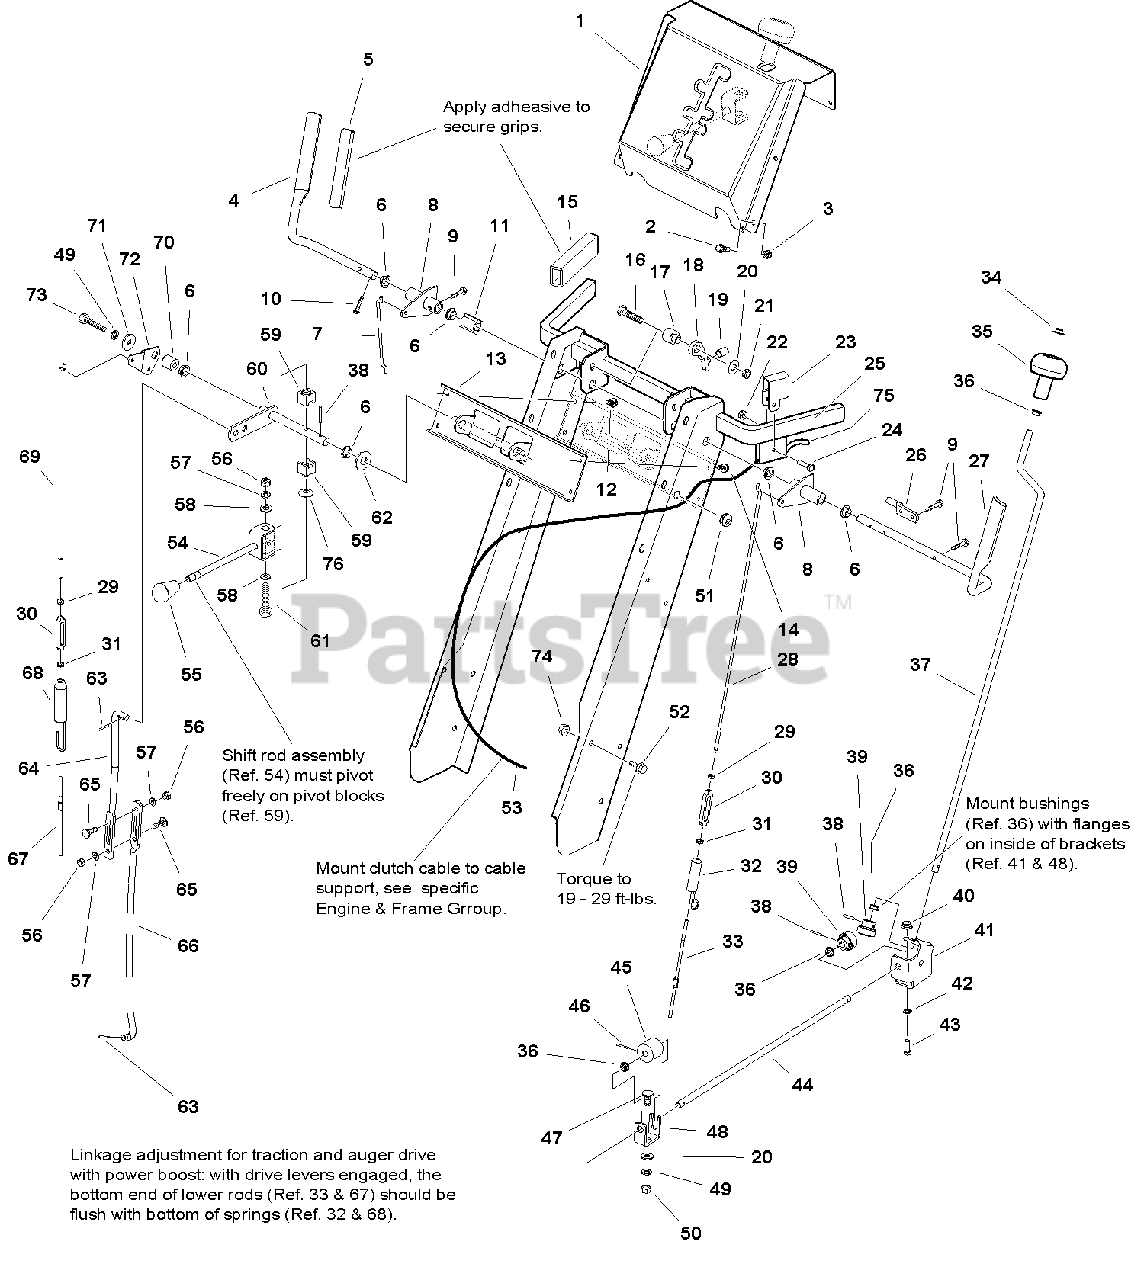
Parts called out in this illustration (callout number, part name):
2	CAPSCREW, Hex Head, 1/4-20 x 3/4
3	NUT, Hex Lock, 1/4-20
4	HANDLE, Clutch, RH
6	BUSHING, Nylon
7	ROD, Clutch
8	LEVER & TUBE ASSEMBLY, Clutch
9	CAPSCREW, Hex Washer Head, #12-24 x 1
10	CAPSCREW, Hex Washer Head, #10-24 x 1
11	GUIDE, Control
12	CAPSCREW, Hex Washer Head, 1/4-20 x 5/8
13	BRACKET, Shift Control
14	CAPSCREW, Hex Head, Taptite, 1/4-20 x 1/2
16	CAPSCREW, Hex Head, 5/16-18 x 1 1/2
17	SPACER
18	LATCH, Control
19	SPRING, Compression
20	WASHER, 5/16
21	NUT, Hex, Center Lock, 5/16-18
22	NUT, Hex Lock, #10-24
23	CLAMP, Clutch Cable
24	SCREW, Pan Head, Phillips, #10-24 x 1
25	HANDLE ASSEMBLY
26	ROD, Control
27	HANDLE, Clutch, LH
28	ROD, 17.3" Long
29	NUT, LH, Machine Screw, Hex, #10-24
31	NUT, RH, Machine Screw, Hex, #10-24
33	ROD, Clutch
34	PUSH NUT
35	KNOB, Spinner
36	BUSHING, Nylon
37	ROD, Chute Control
38	PIN, Cotter
40	NUT, Hex Flange, 1/4-20
41	SUPPORT, Gear
42	PUSH NUT
43	CARRIAGE BOLT, 1/4-20 x 5/8
44	ROD, Chute
46	PIN, Spring, 1/8 x 3/4
47	CARRIAGE BOLT, 5/16-18 x 3/4
48	SUPPORT, Worm
49	LOCKWASHER, Spring, 5/16
50	NUT, Hex, 5/16-18
52	CAPSCREW, Hex Whiz Lock, 5/16-18 x 3/4
53	CABLE & HANDLE ASSEMBLY, Clutch (Includes Ref. 75)
54	SHIFT ASSEMBLY, Rod & Clevis
56	NUT, Hex, 1/4-20
57	LOCKWASHER, Spring, 1/4
58	WASHER, 1/4
59	BLOCK, Pivot
60	ROD & ARM ASSEMBLY, Pivot
61	CAPSCREW, Hex Head, 1/4-20 x 2 1/4
62	WASHER, 1/2
63	PIN, Cotter
64	ROD, Shift, Upper
65	CARRIAGE BOLT, 1/4-20 x 3/4
66	ROD, Shift, Lower
67	ROD, Clutch, Lower
69	ROD, Clutch, Upper
71	WASHER, 5/16
72	LEVER, Clutch
73	CAPSCREW, Hex Head, 5/16-18 x 3/4
74	NUT, Hex Flange, 5/16-18
75	TRIGGER ASSEMBLY, Easy Turn Clutch Cable
76	WASHER, Curved, 1/2
